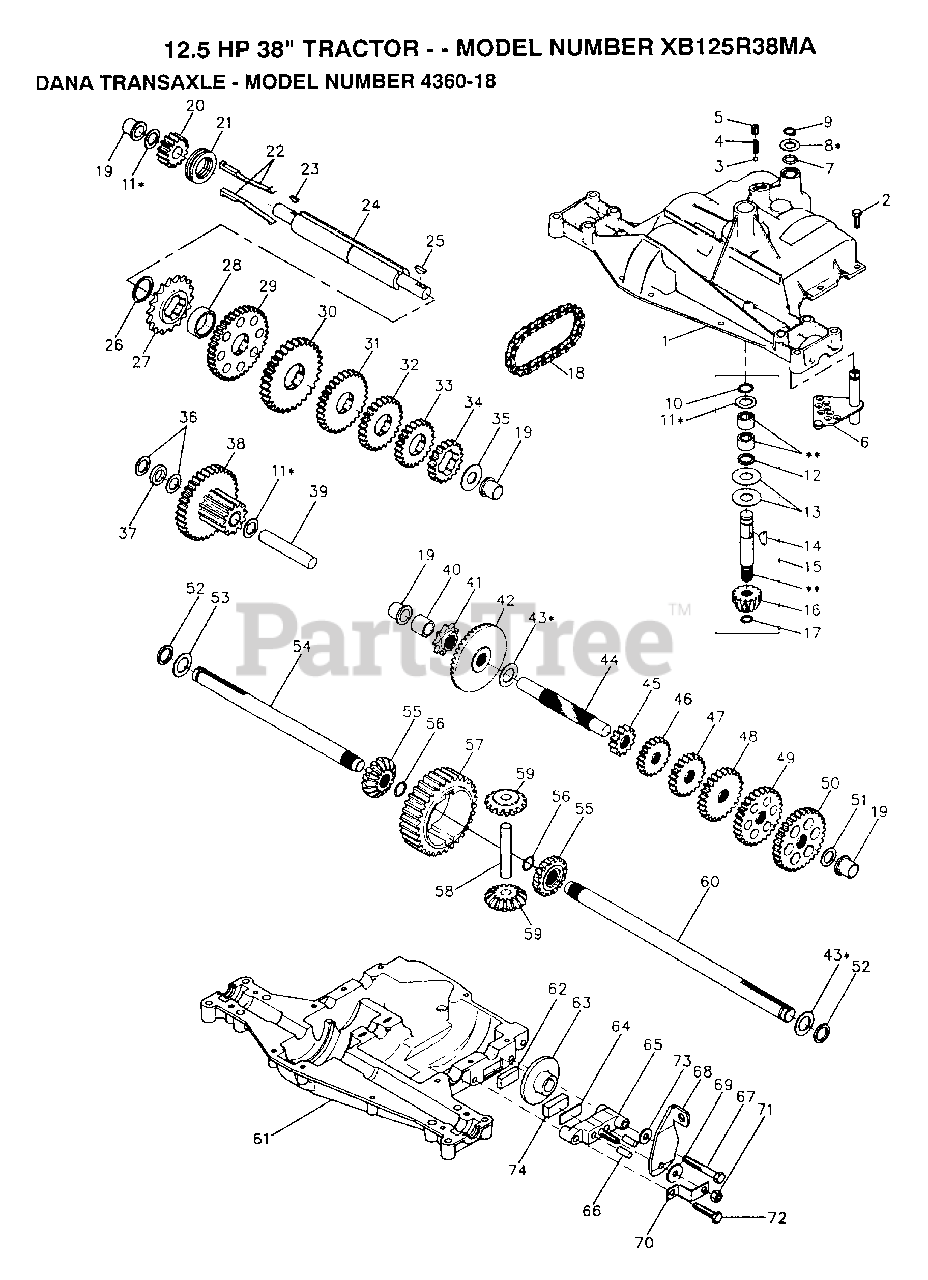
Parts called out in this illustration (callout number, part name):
1	HOUSING UPPER
3	BALL DETENT
4	SPRING, DETENT
5	SCREW, SET
6	ASSY SHIFTER
8	WASHER PLAIN
9	RING RETAINING
10	RING RETAINING
11	WASHER PLAIN
11	WASHER, PLAIN .632 X 1.00 X .026
11	WASHER, PLAIN .632 X 1.00 X .060
13	WASHER, PLAIN .632 X 1.38 X .046
14	KEY WOODRUFF #9
15	ASSY KIT INPUT SHAFT
16	PINION, BEVEL, 14 TEETH
17	RING, RETAINING
18	CHAIN, 24 PITCHES
19	BEARING, FLANGE
20	GEAR SPUR, 14 TEETH
21	COLLAR CLUTCH
22	KEY CLUTCH
23	KEY WOODRUFF #3
24	SHAFT INTERMEDIATE
25	KEY, WOODRUFF, #61
26	RING, RETAINING
27	SPROCKET, 18 TEETH
29	GEAR, SPUR, 37 TEETH
30	GEAR, SPUR, 35 TEETH
31	GEAR, SPUR, 30 TEETH
32	GEAR, SPUR, 25 TEETH
33	GEAR, SPUR, 22 TEETH
35	WASHER, PLAIN .640 X 1.37 X .061
36	WASHER, PLAIN .632 X 1.00 X .026
37	SPACER .630 X 1.00 X .169
38	ASSY GEAR COMB 12&35 TEETH
39	SHAFT IDLER
40	SPACER .635 X .875 X .755
41	SPROCKET, 9 TEETH
42	GEAR, BEVEL, 42 TEETH
43	WASHER PLAIN
43	WASHER, PLAIN .758 X 1.25 X .031
44	SHAFT, DRIVE
45	GEAR, SPUR, 12 TEETH
46	GEAR SPUR, 15 TEETH
47	GEAR, SPUR, 20 TEETH
48	GEAR, SPUR, 25 TEETH
49	GEAR, SPUR, 28 TEETH
50	GEAR, SPUR, 31 TEETH
51	WASHER, PLAIN .632 X 1.00 X .060
53	WASHER PLAIN
54	AXLE LEFT HAND
55	GEAR, MITER, 15 TEETH
56	RING, RETAINING
57	GEAR, SPUR, 32 TEETH
58	SHAFT, CROSS
59	GEAR, MITER, 15 TEETH
60	AXLE RIGHT HAND
61	HOUSING LOWER
62	PUCK, FRICTION
63	DISC, BRAKE
65	JAW, BRAKE
66	PIN, DOWEL
67	SCREW TAPPING
68	LEVER, ACTUATING
69	WASHER, PLAIN .321 X 1.00 X .055
70	BRACKET, ANTI-ROTATION
71	LOCKNUT 5/16-24
72	SCREW TAPPING
73	WASHER PLAIN
74	PUCK, FRICTION
